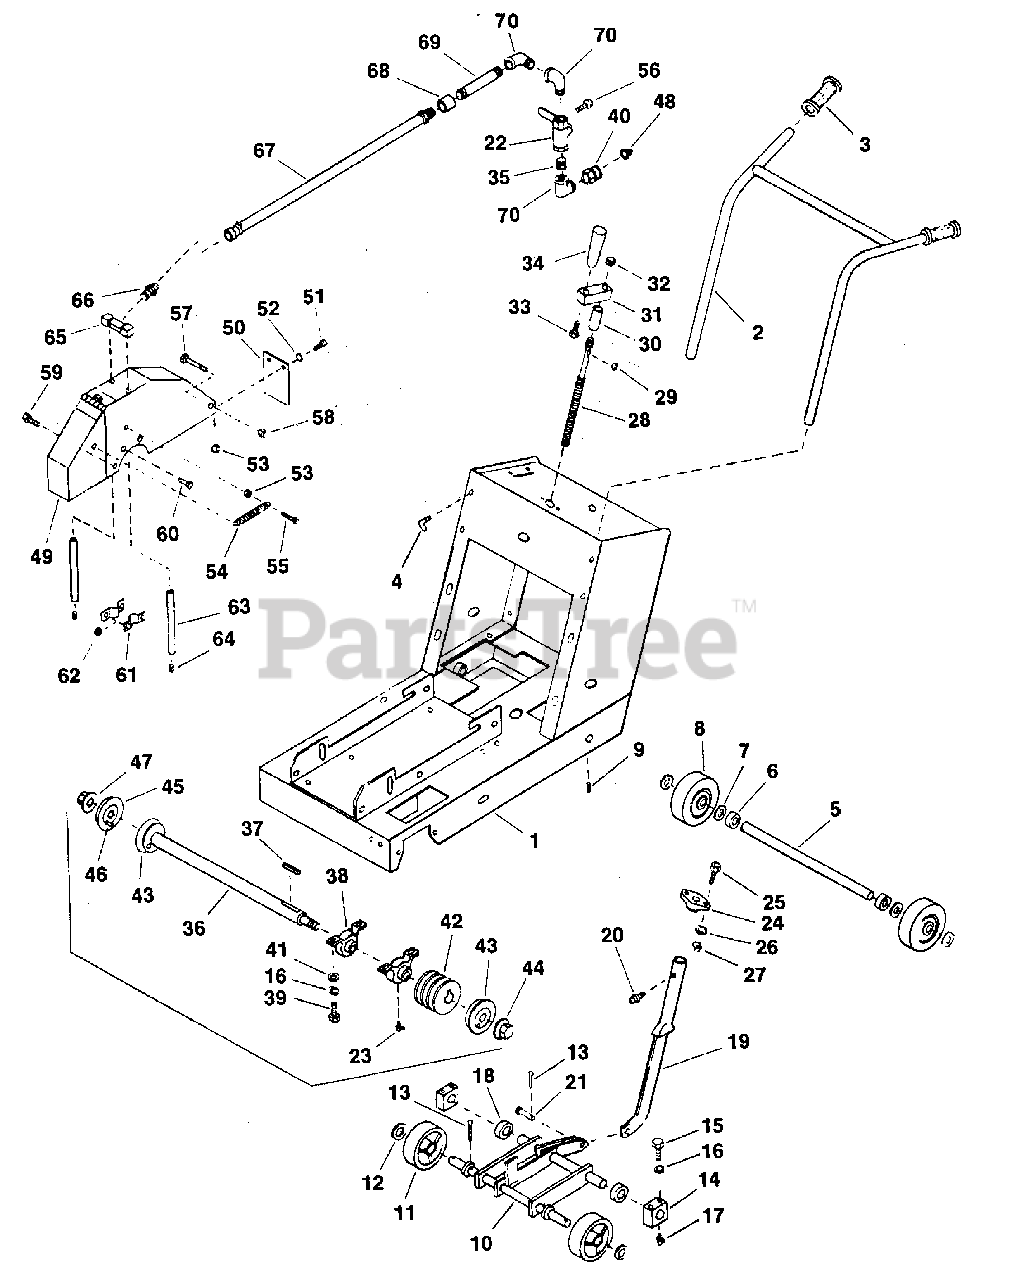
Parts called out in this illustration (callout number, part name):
1	FRAME ASSEMBLY
2	HANDLE BAR
3	GRIP- Handle
4	L-BOLT- 3/8-16
5	AXLE- Rear
6	SET COLLAR- (with Setscrews) 5/8"
7	WASHER- Flat 5/8" Dia.
8	WHEEL- 6" Dia.
9	SETSCREW- 1/4-20 x 1/4"
10	AXLE- Front Weldment
11	WHEEL- 5" Dia.
12	WASHER- Sae 3/4" Dia.
13	PIN- Cotter 1/8 x 1"
14	BLOCK- Pivot with Bushing and Grease Fitting
15	CAPSCREW- Hex Hd. 3/8-16 x 1" Grd. 5
16	WASHER- Lock, Split Type 3/8" Dia.
17	FITTING- Grease
18	COLLAR- Set 1"
19	SHAFT- Adjustment (includes Grease Fitting)
20	FITTING- Grease
21	PIN- Clevis
22	VALVE- Water
23	FITTING- Grease
24	BLOCK- Bearing Flange
25	CAPSCREW- Hex Hd. 1/4-20 x 1" Grd. 5
26	WASHER- Sae 1/4" Dia.
27	LOCKNUT- Fiber Type 1/4-20
28	SCREW- Adjustment
29	KEY- Woodruff 1/8 x 5/8"
30	SPACER- Tube
31	HANDLE- Base
32	NUT- Cap
33	BOLT- Shoulder 3/8-16 x 1 1/4"
35	NIPPLE- Close 1/2" NPT
36	SHAFT- Blade
37	KEY- 1/4 x 2 1/2"
38	BEARING- Pillow Block
39	CAPSCREW- Hex Hd. 3/8-16 x 1 1/4" Grd. 5
40	FITTING- 3/4" Garden Hose Swivel To 1/2" Female Pipe
41	WASHER- Sae 3/8" Dia.
43	FLANGE- Inner
44	NUT- Flange, R.H,
45	FLANGE- Outer with Pin
47	NUT- Flange, L.H.
48	FILTER- Hose Washer
49	GUARD- Blade
50	FLAP- Splash
51	CAPSCREW- Hex Hd., #10-24 x 3/4" Grd. 5
52	WASHER- Flat #10
53	NUT- Hex #10-24 Unc.
55	CAPSCREW- Hex Hd. #10-24 x 3/4" Grd. 5
56	SCREW- Round Hd., Mach. #10-24 x 3/8"
57	CAPSCREW- Hex Hd. 3/8-16 x 3 3/4" Ig.
58	LOCKNUT- Fiber Type, 3/8-16
59	CAPSCREW- Hex Hd., 5/16-18 x 3/4" Grd. 5
60	SCREW- Flat Hd. Mach. 1/4-20 x 3/4" lg.
61	CLAMP- Water Tube
62	LOCKNUT- Fiber Type 1/4-20
63	TUBE- Water
64	PLUG- Pipe
65	MANIFOLD
66	ADAPTOR- Hose
67	HOSE ASSEMBLY
68	COUPLING- Pipe 1/2" NPT Galvanized
69	NIPPLE- Pipe 1/2" NPT x 41/2" lg.
70	ELBOW- Street 1/2" NPT Galvanized
